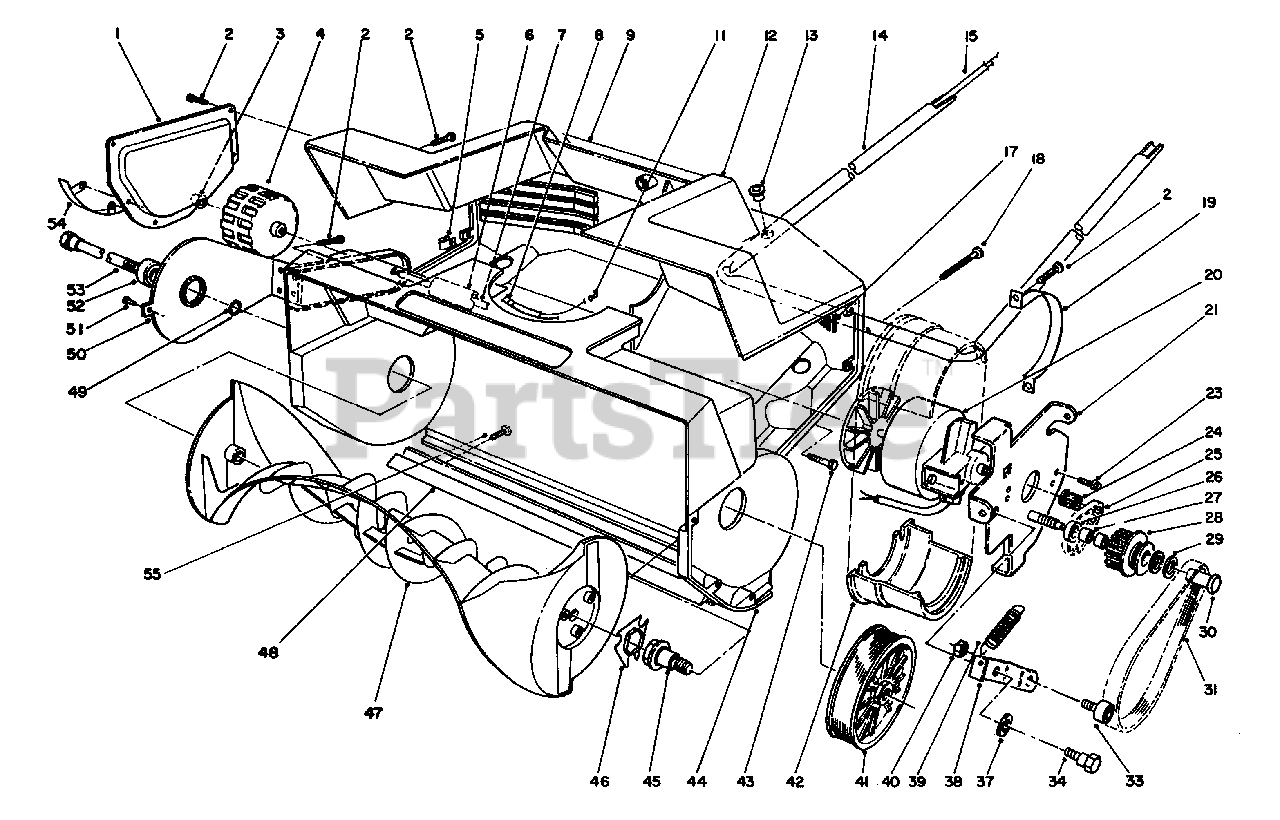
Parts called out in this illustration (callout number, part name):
1	Plate-Side
2	Screw-Pan Hd.
3	Push Nut
5	U-Clip-Tinnerman
6	Sleeve-Axle
7	Shaft-Axle
8	Relief-Strain
9	Decal-Danger
11	Connector
12	Shroud-Housing
14	Tube-Lower Handle
15	Wire Harness
17	Filter-Foam
18	Screw-Pan Hd.
19	Strap-Motor
21	Motor Plate Assembly
23	Screw-Hex. Washer Hd.
24	Pulley-Driver
25	Belt-Timing
27	Bearing-Needle
28	Pulley Assembly-Idler (Incl. Ref. #27)
29	Washer-Thrust
30	Bolt-Idler
31	Belt-Drive
33	Bearing Assembly (Incl. Ref. #40)
34	Screw-Shoulder
38	Bracket-Idler
40	Nut-Lock
41	Pulley-Driven
42	Clamp-Motor Bracket
43	Screw-Hex. Hd.
44	Housing-Rotor
45	Shaft-Rotor Driver
46	Coupler-Rotor
47	Rotor
50	Bracket-Wheel (Incl. Ref. #52)
51	Rivet-Pop
52	Bearing-Ball
53	Shaft-Rotor
54	Skid-Housing
55	Screw-Pan Hd.
